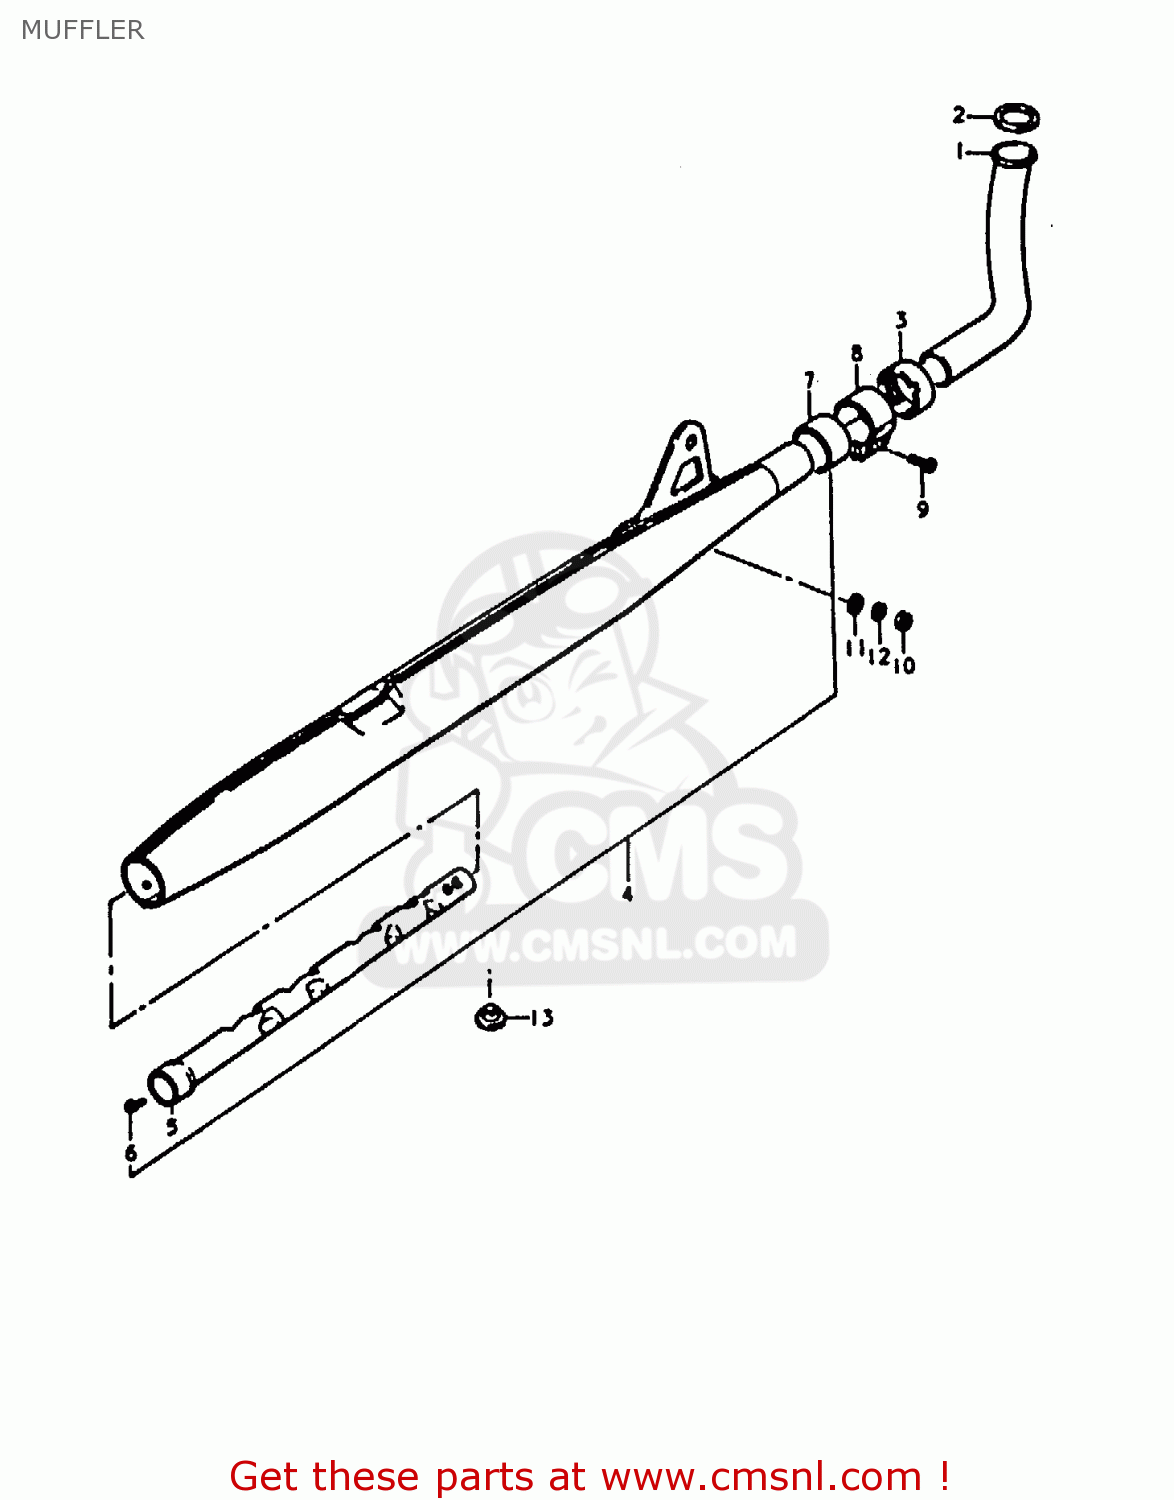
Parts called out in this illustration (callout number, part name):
1	PIPE,EXHAUST
2	GASKET,EXHAUST PIPE
3	CLAMP,EXHAUST PIPE
4	MUFFLER ASSEMBLY
5	PIPE,MUFFLER BAFFLE
6	SCREW
7	CONNECTOR,MUFFLER
8	CLAMP
9	SCREW
10	NUT
11	WASHER
12	LOCK WASHER
13	CUSHION
